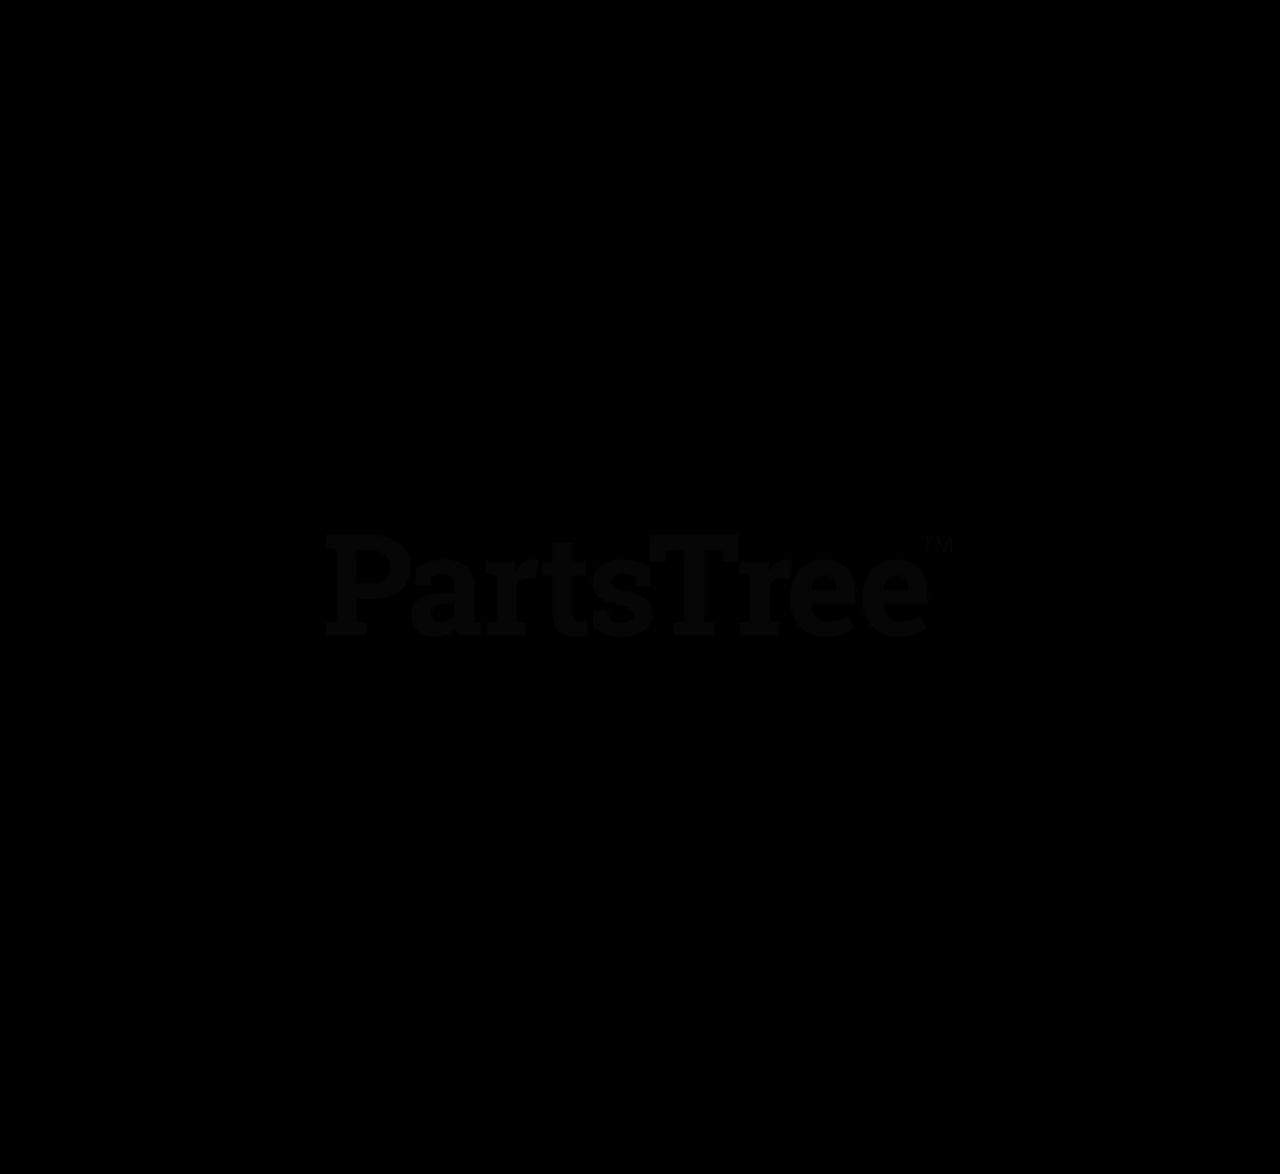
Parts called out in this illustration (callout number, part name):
1	Decal, Lift Lever
2	Decal, 60" (215)
3	Decal, Parking Brake Lever
4	Decal, Maintenance Instructions
5	Decal, Diesel Control Panel
6	Decal, Height of Cut
7	Decal, Belt Diagram
8	Decal, Pro-Master 260 (215)
9	Decal, Gravely Heritage - Large
10	Decal, Pinch Point
11	Decal, Seat Release
12	Decal, X-Factor Deck
